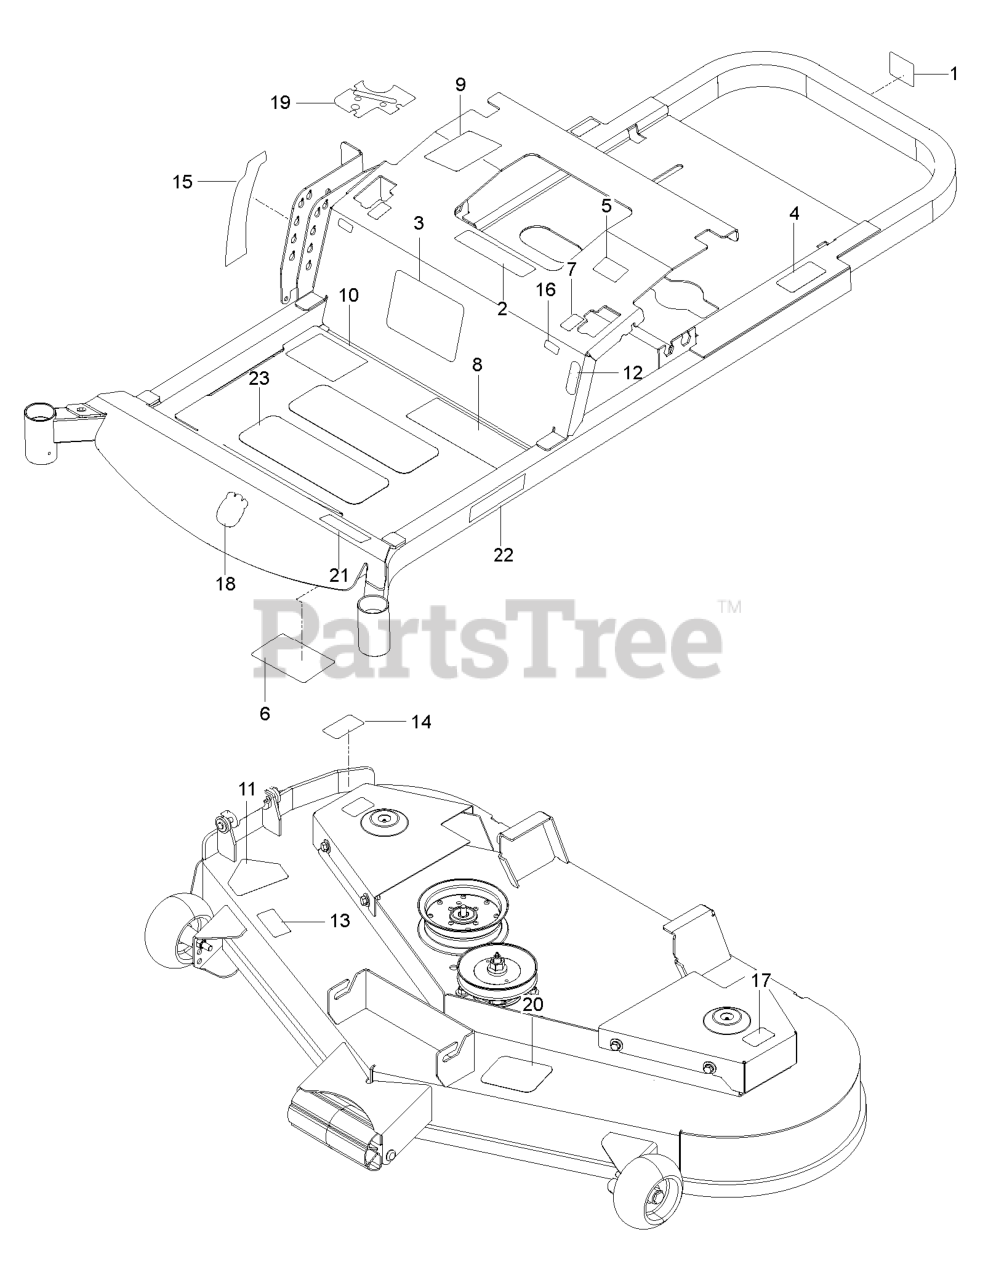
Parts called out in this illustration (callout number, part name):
1	DECAL, PROP. 65
2	EURO DECAL-BATTERY WARNIN6
3	DECAL, START
4	DECAL, DO NOT TOW
5	DECAL, EXITING MOWER
6	DECAL, SERVICE
7	DECAL, MOTION CONTROL
8	DECAL, SAFETY WARNING
9	DECAL, CUSTOMER RESPNSIBILITY
10	DECAL, WARNING
11	DECAL, CPSC
12	DECAL, PARK BRAKE
13	DECAL, EURO SEVERING
14	DECAL, CAUTION
15	DECAL, HEIGHT
16	DECAL, F.S.T.
17	DECAL, NO STEP
18	DECAL.AUGER.HUSQ.CROWN.SNOW
19	DECAL, CTRL PANEL, HUSQ
20	DECAL, BELT ROUTING
21	DECAL, RZ5424
22	RP.DECAL.BADGE.170MM.TEXTLOGO
23	ANTI-SKID PAD
